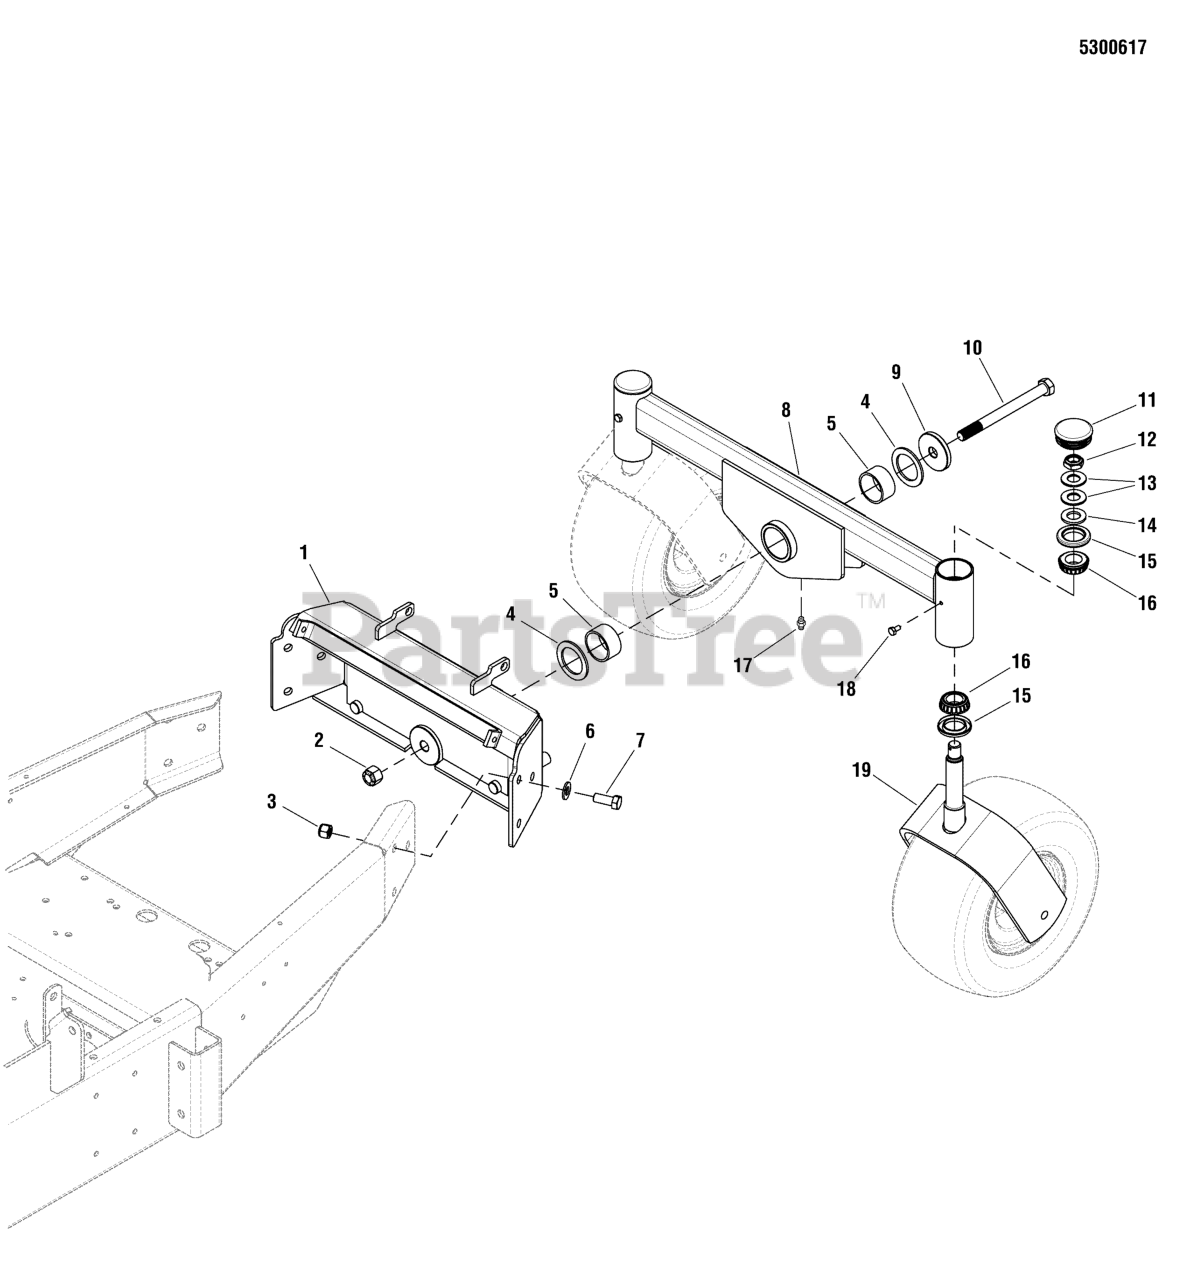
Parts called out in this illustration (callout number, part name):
2	NUT, 5/8-11 HEX NYLON LOCK
3	NUT, Hex, Nylon Lock, 1/2-20
4	THRUST WASHER 1-3/4 X 2-1/2 X 1/8
5	BUSHING, 1-3/4 X 2 X 1
6	WASHER, 1/2 SAE
7	BOLT, 1/2-20 X 1-1/4" GD5 CZ
8	ASSM, TAIL WHEEL MOUNT - S800X
9	WASHER, .656 X 2.44 X .31, YZ
10	BOLT, HEX HD, 5/8-11 X 7 GD5 YZ
11	CAP, GREASE, LOW PROFILE
12	NUT, 3/4-16, HEX JAM NYLON LOCK
13	WASHER, BELLEVILLE - 1.500 X .755
14	WASHER, 3/4 SAE
15	SEAL, GREASE
16	BEARING, TAPERED ROLLER, 1
17	GREASE FITTING, 1/4-28 STRAIGHT
18	BOLT, 1/4-28 X 1/2, GD5 YZ
19	WELD, CASTER YOKE - RED
